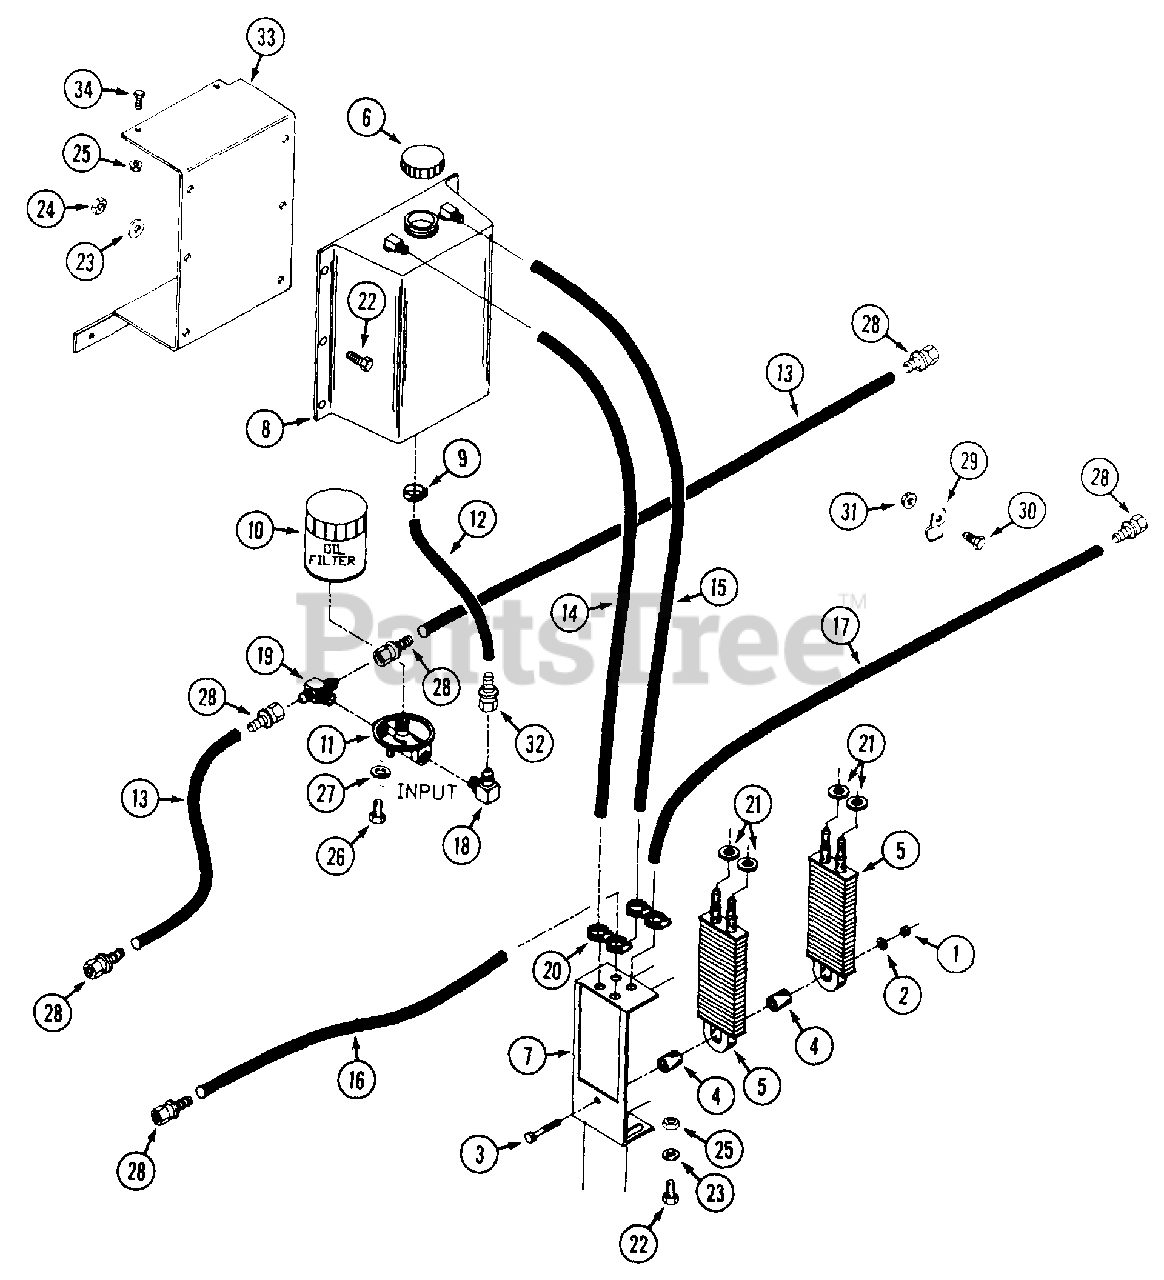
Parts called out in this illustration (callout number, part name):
1	NUT - lock 5/16"
2	WASHER - 5/16"
3	BOLT - 5/16" - 18 x 2-3/4"
4	BUSHING - rubber
6	CAP - oil tank
7	MOUNT - oil cooler
8	TANK - oil
9	CLAMP - hose 5/8"
10	FILTER - oil
11	HEAD - oil filter
12	HOSE - 5/8" x 11"
13	HOSE - hydraulic 3/8" x 13"
14	HOSE - hydraulic 3/8" x 25"
15	HOSE - hydraulic 3/8" x 27"
16	HOSE - hydraulic 3/8" x 38"
17	HOSE - hydraulic 3/8" x 24"
18	FITTING - male 90° adapter
19	FITTING - male tee adapter
20	CLAMP - hose 3/8"
21	GROMMET - 1/2" ID x 1" OD
22	BOLT - 1/4"-20 x 3/4"
23	WASHER - 1/4"
24	NUT - 1/4"-20 lock
25	NUT - 1/4"-20 flange lock
26	BOLT - 1/4"-20 x 3/4" self-tap
27	LOCKWASHER - 1/4"
28	FITTING - 3/8" hose barb x 3/8" FM JIC
29	CLIP - "J"
30	BOLT - 5/16" x 18 x 3/4"
31	NUT - 5/16"-18 flange lock
32	FITTING - 5/8" hose barb x 1/2" FM JIC
33	MOUNT - oil tank
34	BOLT - 1/4"-20 x 1/2"
